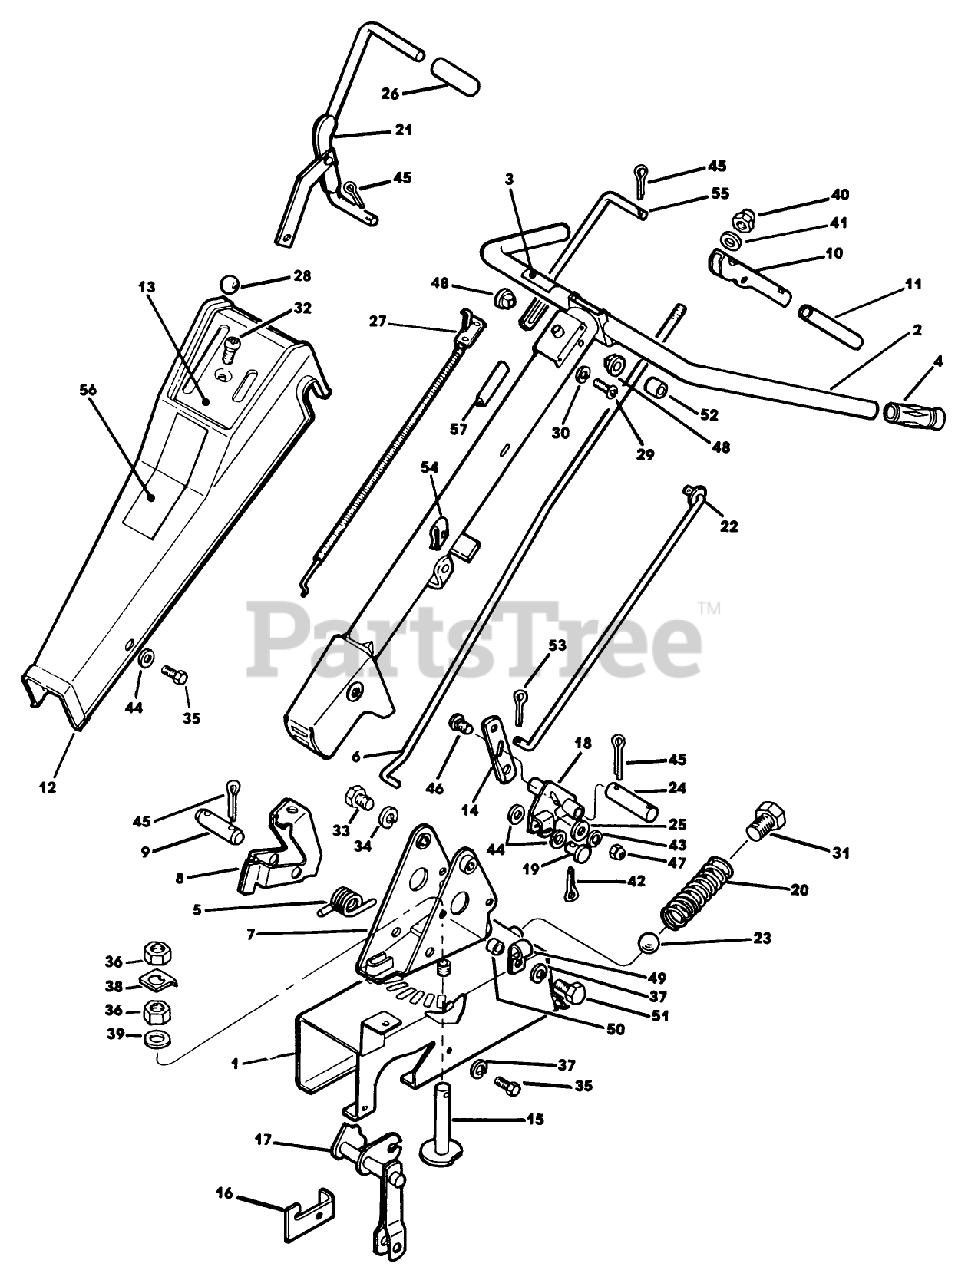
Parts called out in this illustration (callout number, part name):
6	CONTROL ROD
20	DETENT SPRING
27	THROTTLE CONTROL
34	WASHER
35	SCREW-HH
40	NUT-LOCKING
41	WASHER
43	Washer, Lock
47	NUT
51	SCREW
54	NUT-SPEED
